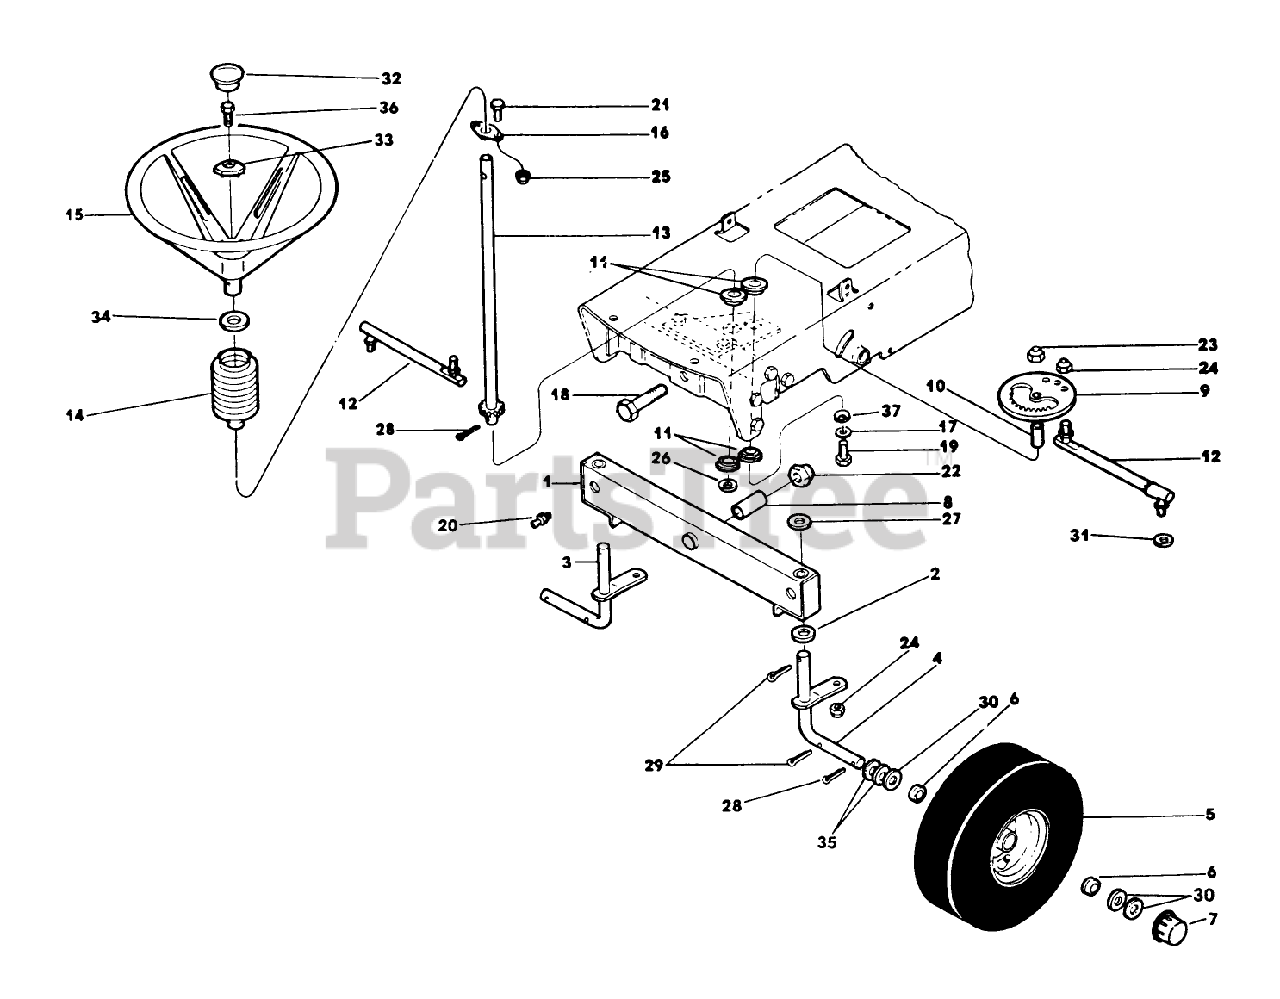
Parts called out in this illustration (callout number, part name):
8	SPACER
10	SPACER
11	BEARING - FLANGE
13	STEERING SHAFT WA
16	BEARING AY.
17	WASHER
21	SCREW-HH
22	NUT-HEX CONE LOK
23	NUT-HEX
24	HEX NUT
25	NUT-LOCK, CONE
26	SPACER
30	WASHER
32	CAP
36	SCREW - HEX
